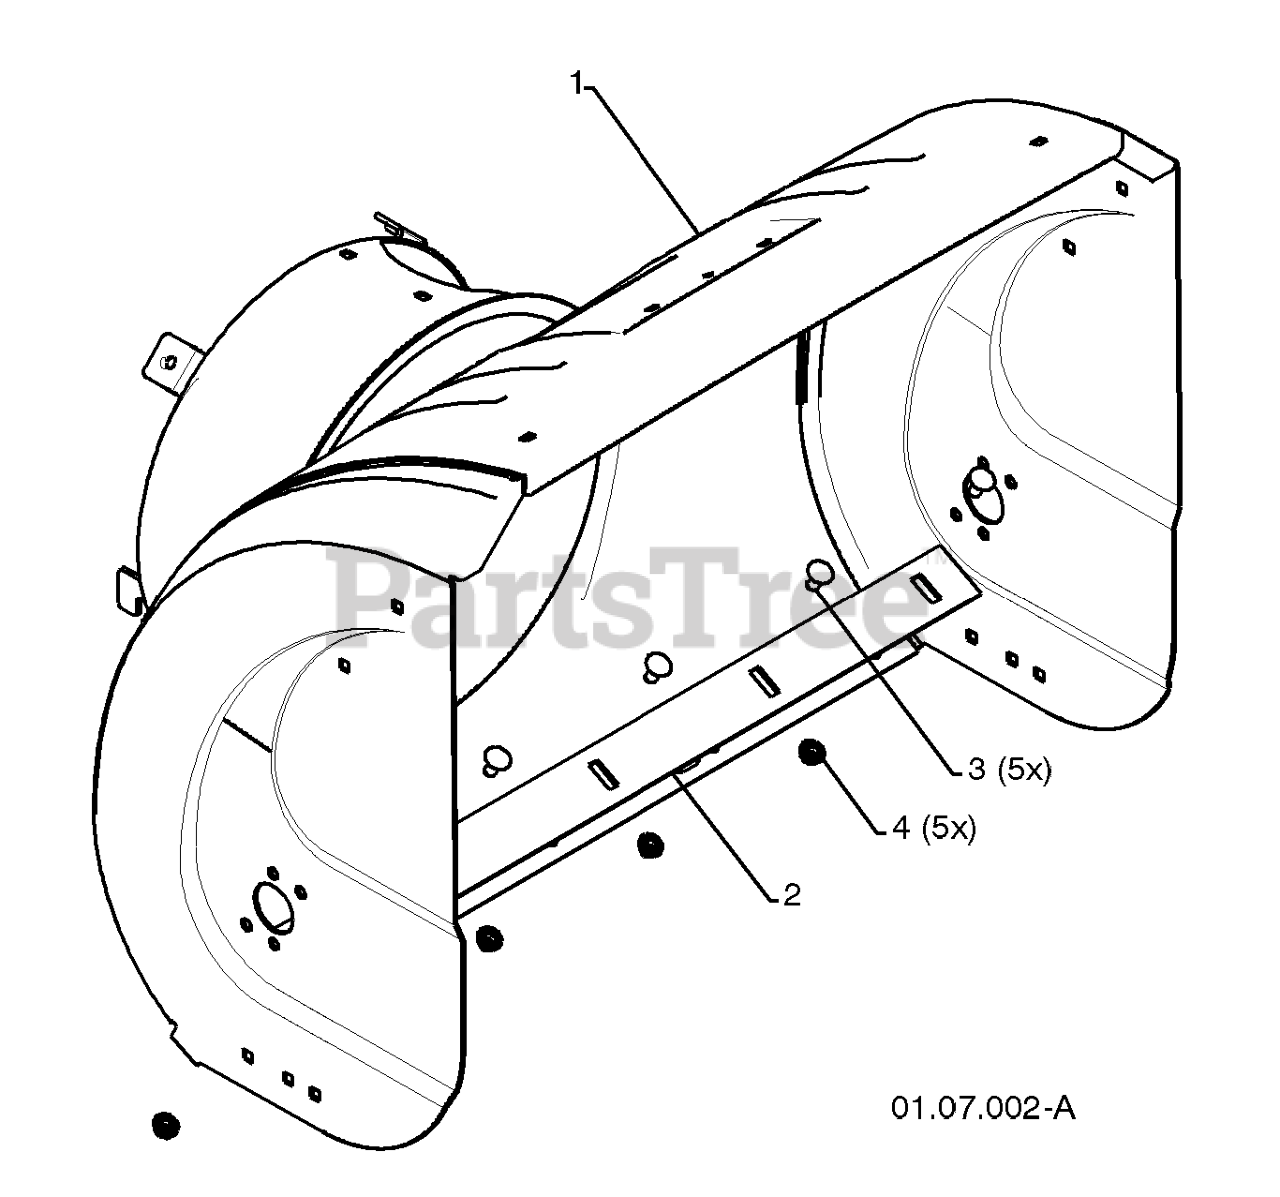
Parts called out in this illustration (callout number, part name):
1	HOUSING, AUGER
2	BAR, SCRAPER
3	BOLT
4	NUT.FLANGE.5/16
